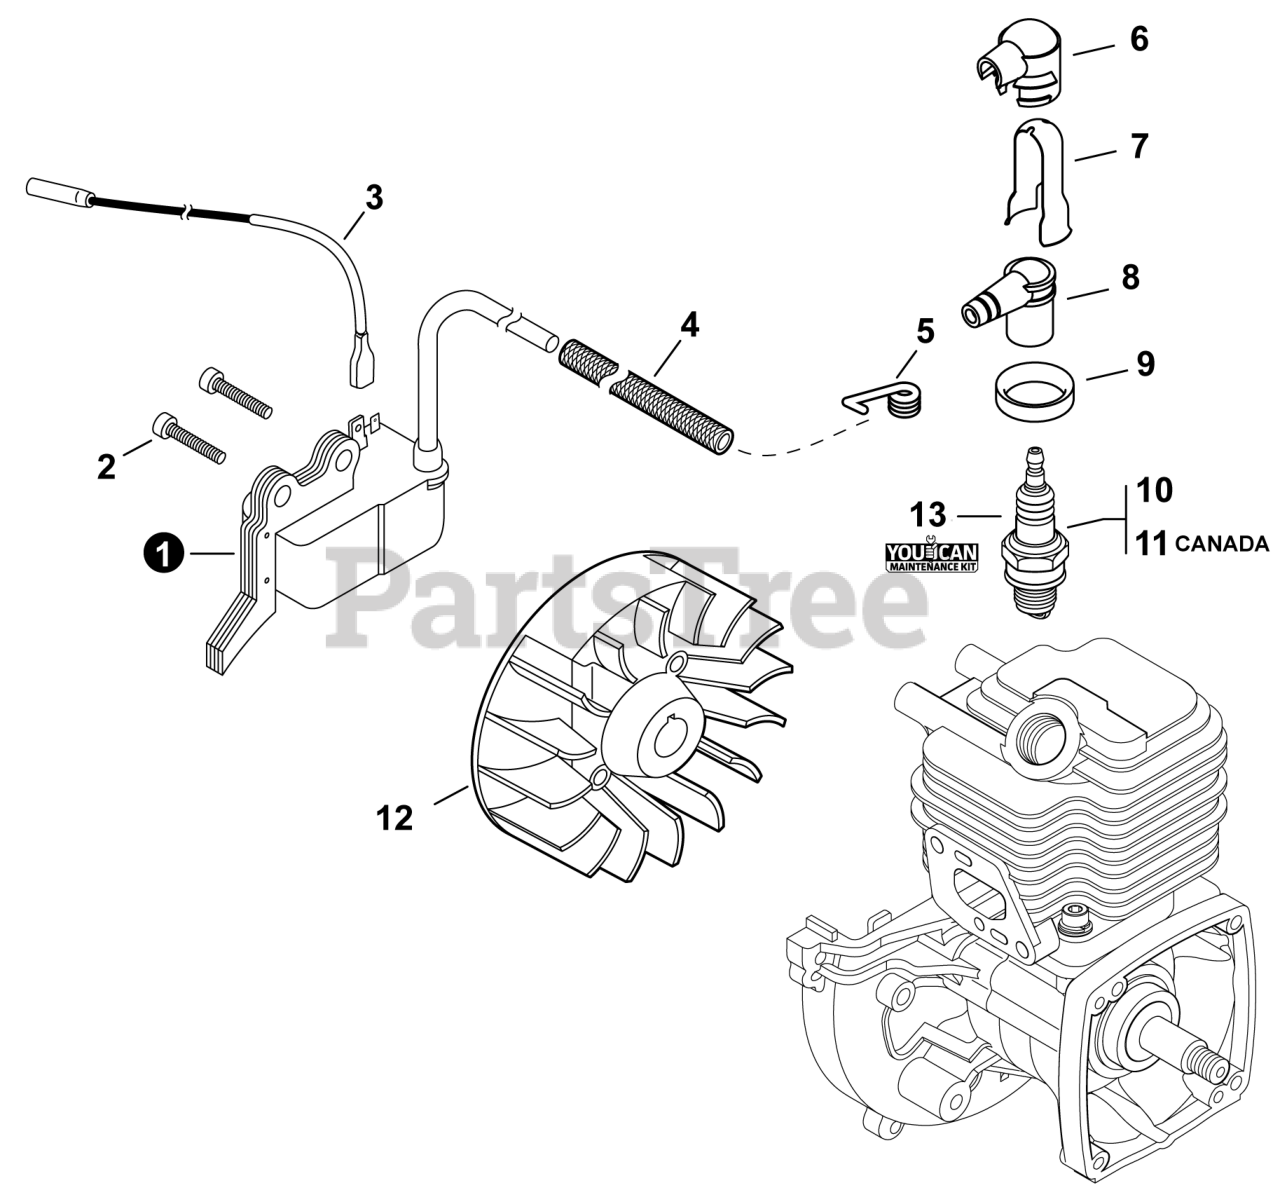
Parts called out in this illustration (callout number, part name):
1	COIL, IGNITION
2	BOLT, TORX 4x20
3	LEAD - IGNITION L= 210
4	TUBE, INSULATOR
5	TERMINAL, SPARK PLUG
6	COVER, CAP
7	SHIELD, SPARK PLUG
8	CAP, SPARK PLUG
9	SEAL, SPARK PLUG
10	SPARK PLUG - BPM8Y
11	SPARK PLUG - BPMR8Y
12	FLYWHEEL
13	TUNE-UP KIT - YOUCAN™
